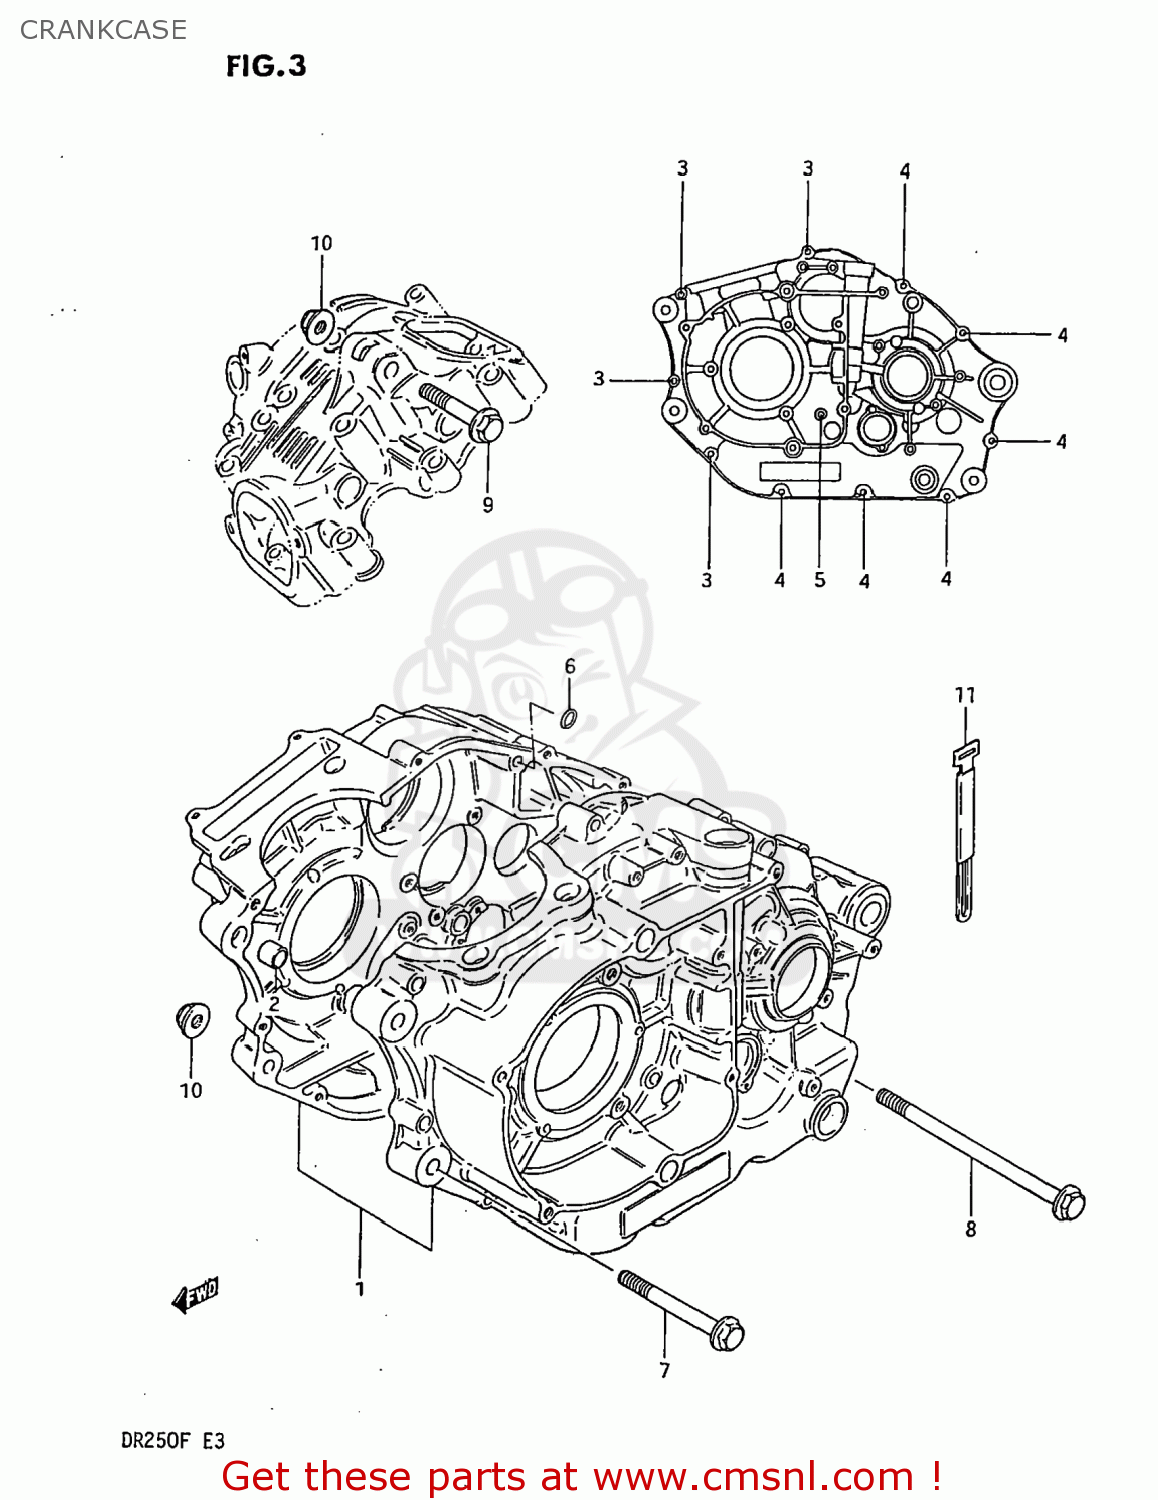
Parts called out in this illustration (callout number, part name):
1	CRANKCASE ASSEMBLY
2	PIN
3	BOLT 6X35
4	BOLT
5	BOLT (6X55)
6	O-RING
7	BOLT 8X67
8	BOLT
9	BOLT 8X50
10	NUT
